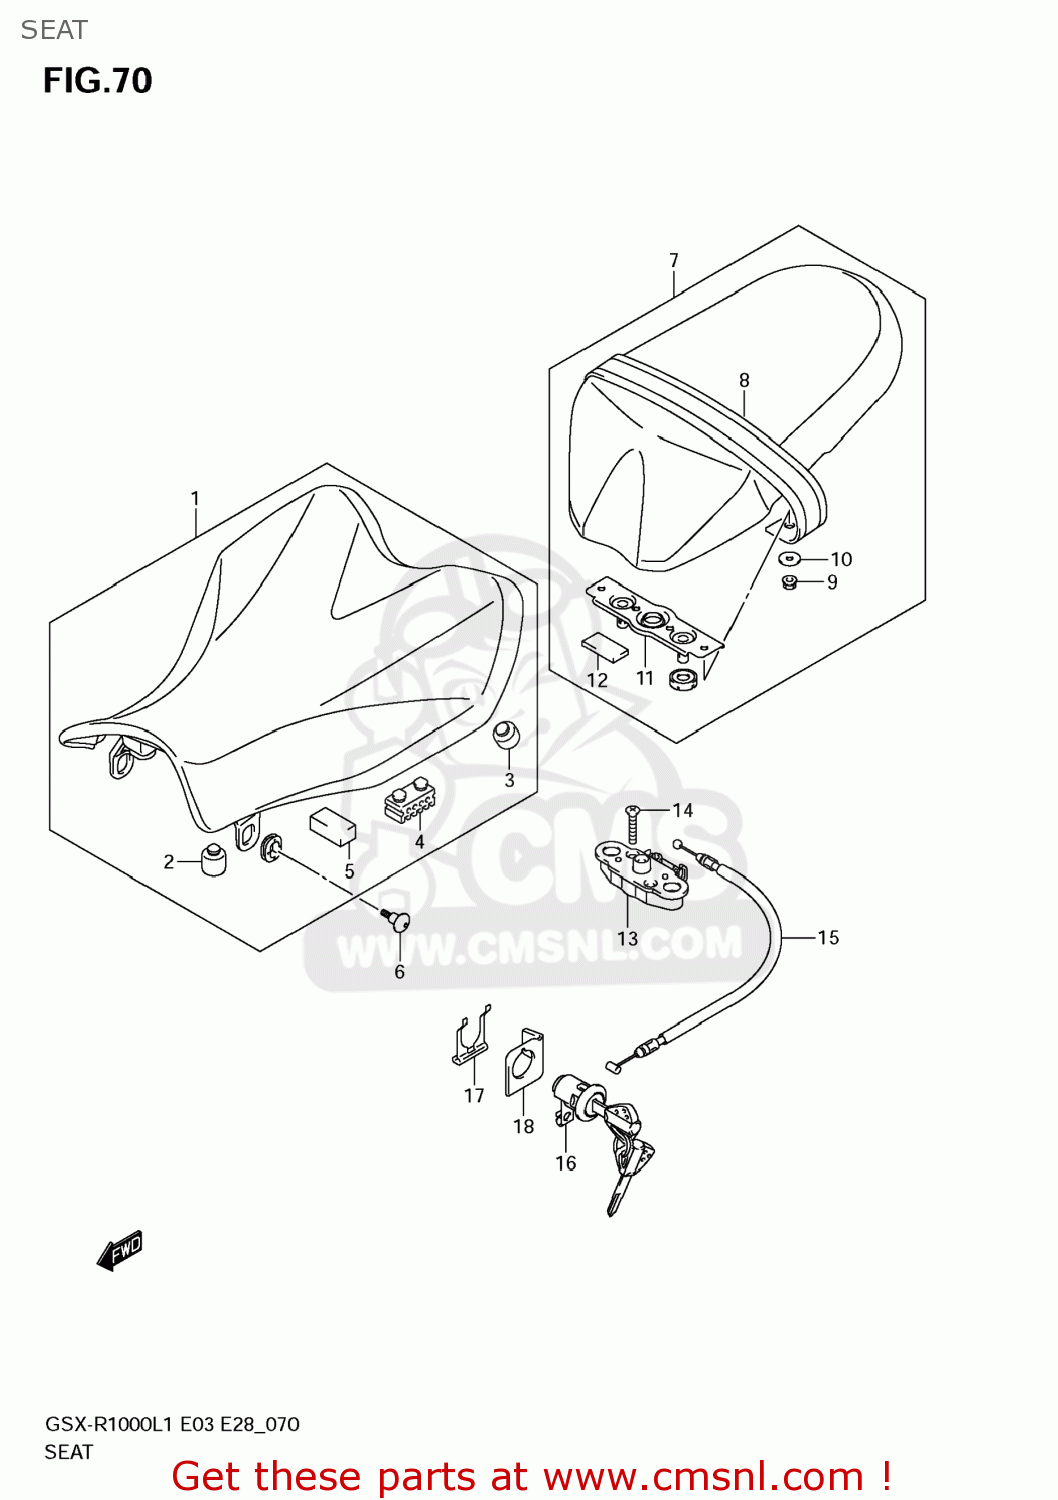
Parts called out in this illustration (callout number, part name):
1	BUDDYSEAT
2	CUSHION
3	CUSHION
4	CUSHION,SIDE
5	CUSHION,FR(20X40X15)
6	SCREW(6X20)
7	DUOZIT
8	BAND ASSY,SEAT(BLACK)
9	NUT
10	WASHER(6.5X20X1.6)
11	STRIKER
12	CUSHION,FR(20X40X15)
13	BRACKET,SEAT SUPPORT
14	SCREW
15	CABLE,SEAT LOCK
16	LOCK SET,SEAT
17	PLATE,SEAT LOCK ASSY
18	GUIDE,SEAT LOCK CABLE
